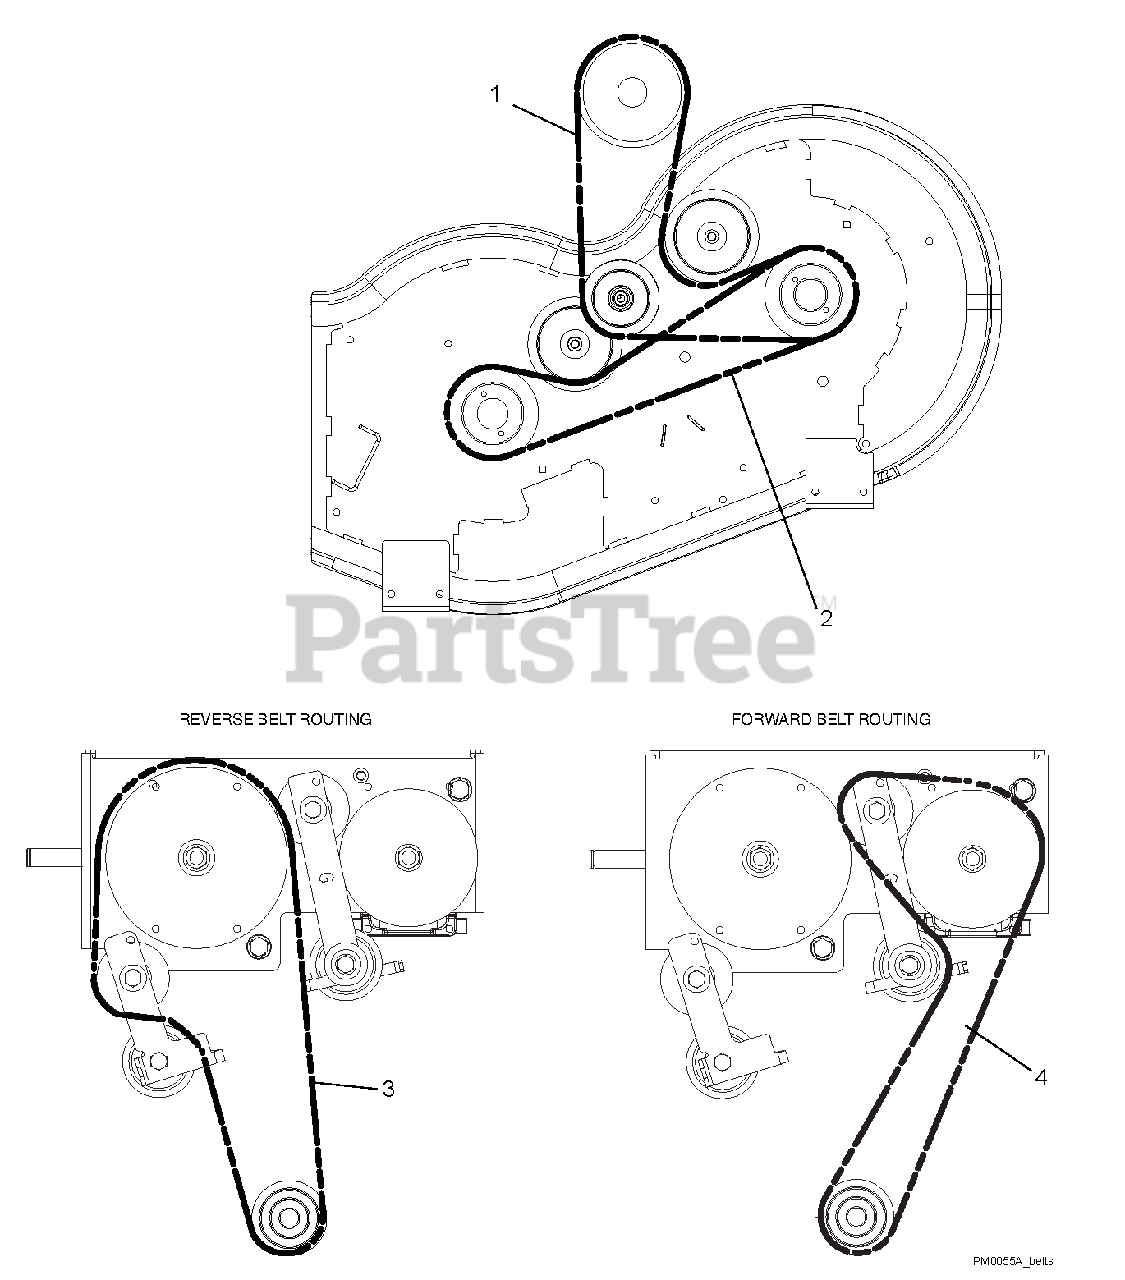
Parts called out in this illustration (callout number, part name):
1	V-BELT, HA WRAPPED
2	V-BELT, HA-WRAPPED
3	V-BELT, 3L-WRAPPED
4	V-BELT, 3L-WRAPPED
